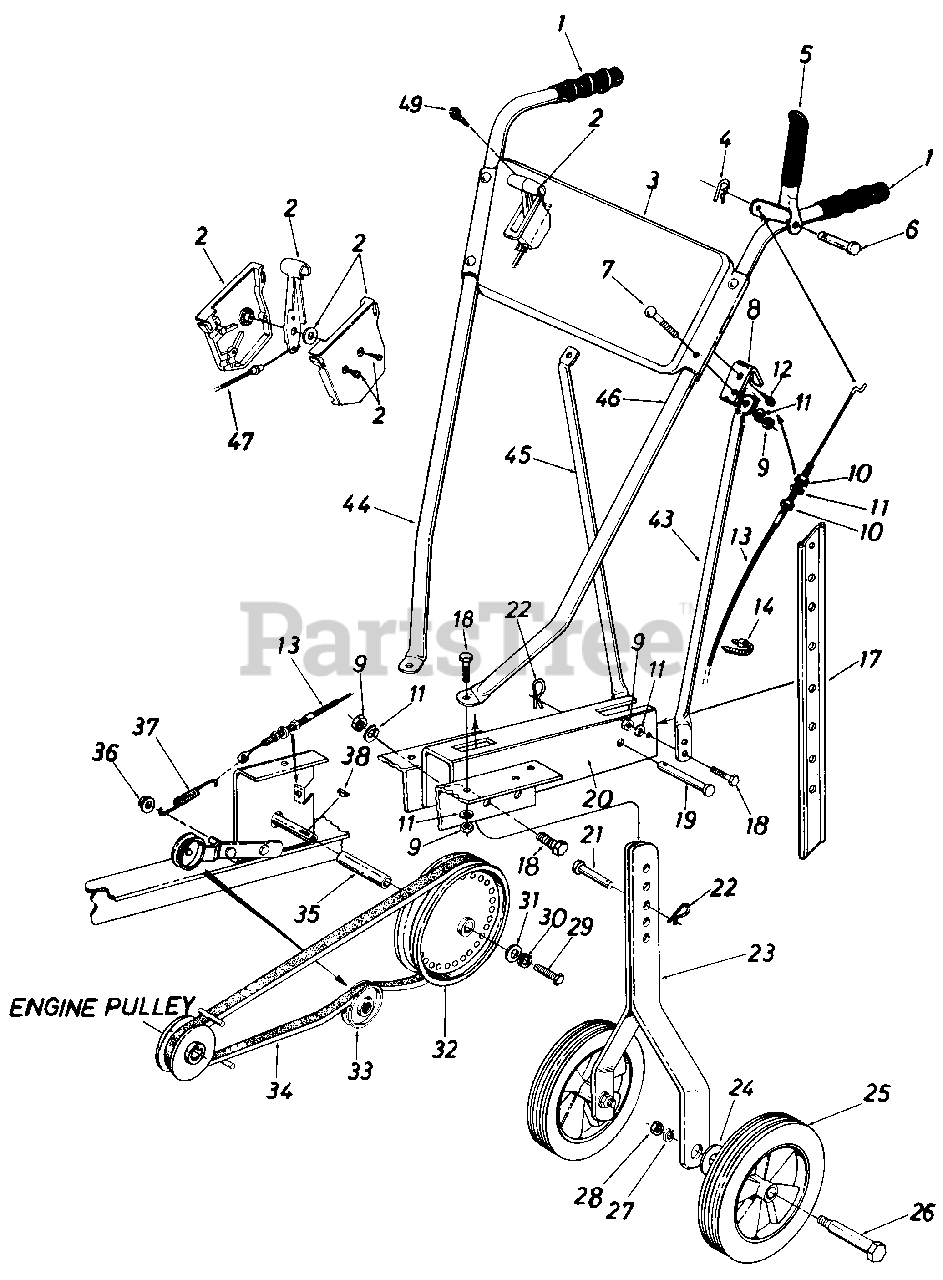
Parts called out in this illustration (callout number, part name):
2	Throttle Control Box
3	Handle Panel
4	Int. Cotter Pin
5	Clutch Grip Ass'y.
6	Clevis Pin
7	Carriage Bolt 5/16-18 x 1.75" Lg.
8	Cable Support Brkt.
9	Hex Nut 5/16-18 Thd.*
10	Hex Jam Nut 5/16-24 Thd.
11	L-Wash. 5/16" I.D.
12	Hex Wash. Hd. Self-Tap Scr. 1/4-20 x .50" Lg.
13	Clutch Control Cable
14	Cable Tie
17	Depth Bar
18	Hex Bolt 5/16-18 x .75" Lg.
19	Clevis Pin 1/2" Dia. x 2.50" Lg.
20	Tailpiece Ass'y.
21	Clevis Pin 818n Dia. x 2.50" Lg.
22	Hairpin Cotter
23	Wheel Bracket Ass'y.
24	Belleville Wash. 1/2" I.D.
25	Wheel Ass'y. Comp.-Plastic
26	Shoulder Bolt
27	L-Wash. 1/2" I.D.
28	Hex Nut 1/2-20 Thd.*
29	Hex Bolt 1/4-28 x .75" Lg.
30	L-Wash. 1/4" I.D.
31	Fl-Wash. .25" I.D. x .930n O.D.
32	Pulley 6.00" O.D.
33	Idler Pulley
34	"V"-Belt 1/2" Pitch x 39" Lg.
35	Spacer
36	Cap Speed Nut
37	Extension Spring
38	Hi-Pro Key
43	Handle Support Bracket-L.H.
44	Handle Bar-R.H.
45	Handle Support Bracket-R.H.
46	Handle Bar-L.H.
47	Throttle Control Cable-35"
49	Self-Tap Scr. #10 x 1/2" Lg.
